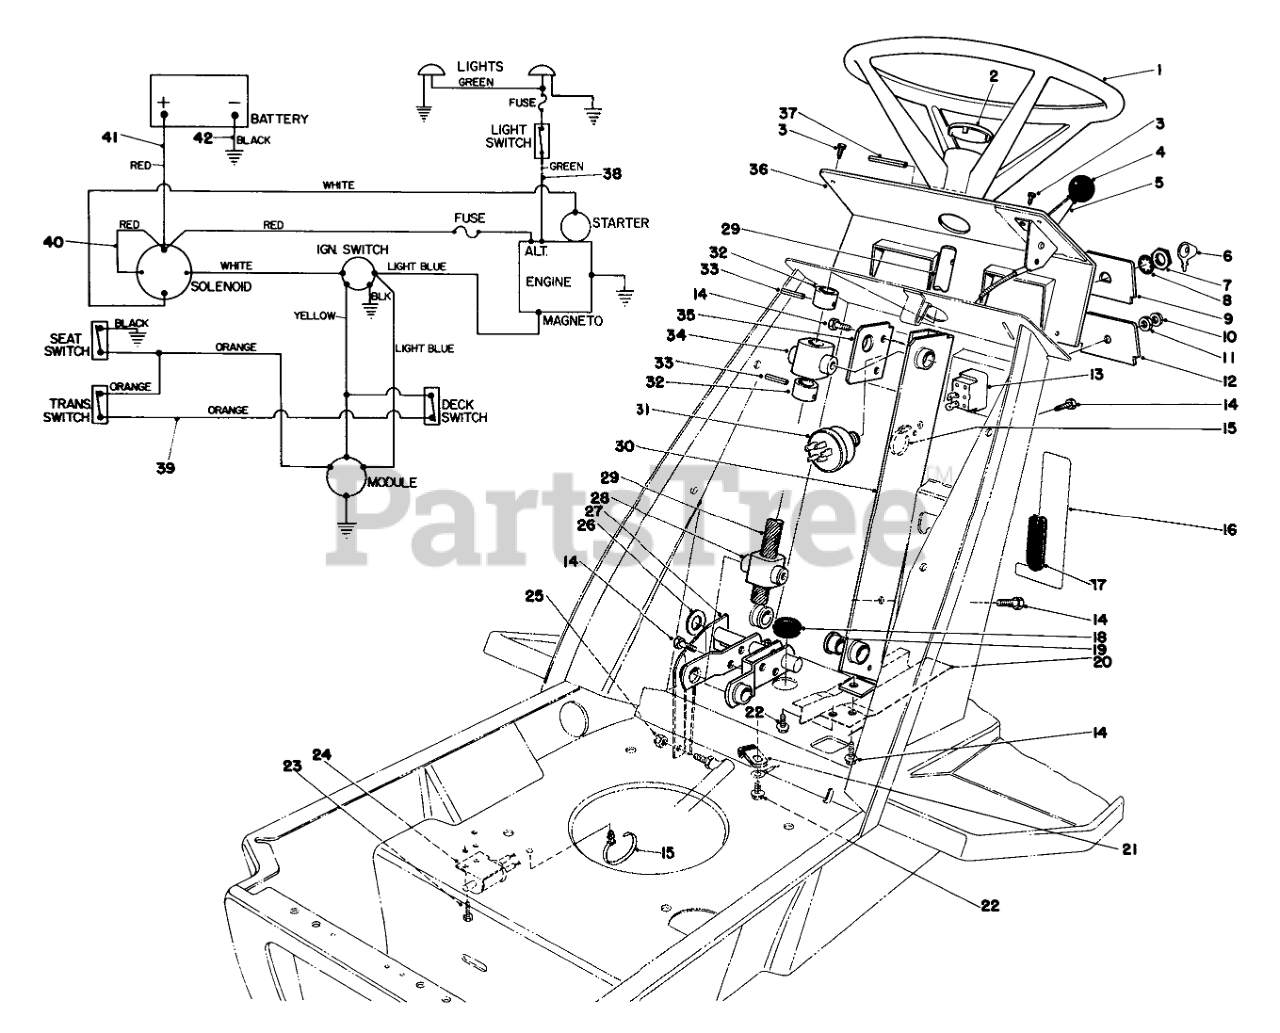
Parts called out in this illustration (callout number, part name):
1	Steering Wheel
2	STRG WHEEL INSERT
3	SCREW-HWHTF
4	KNOB-CONTROL
5	Throttle Control (Incl. Ref. #4)
6	Key
7	NUT-HH
8	WASHER-TOOTH, INTERNAL
9	DASH PANEL INSERT
10	NUT-BULB
11	NUT-LOCK
12	DASH PANEL INSERT
13	Light Switch (Incl. Ref. #10 & 11)
14	SCREW-HWHTF
15	TIE-MOUNT, PUSH
16	Decal-Deck
17	EDGE MOULDING
18	GROMMET
19	BEARING-FLANGE
20	WIRE HARNESS SHLD B
21	CLIP-FUEL LINE
22	SCREW-HWH
23	SCREW-TAPTITE
24	DECK INTERLOCK SWITCH
25	Nut
26	WASHER
27	STEERING LINK WA BO
28	FOLLOWER STEER SHAFT
29	STEERING SHAFT
30	STRG BRKT B
31	Ignition Switch (Incl. Ref. #6-8)
32	STRG SHAFT COLLAR
33	PIN-SPRING
34	BRG STEERING SHAFT
35	STRG BRG SUPPORT
36	DASH PANEL
37	PIN-ROLL
38	WIRE HARNESS
39	Wire Harness
40	SOLENOID WIRE
41	WIRE ASM
42	WIRE ASM
